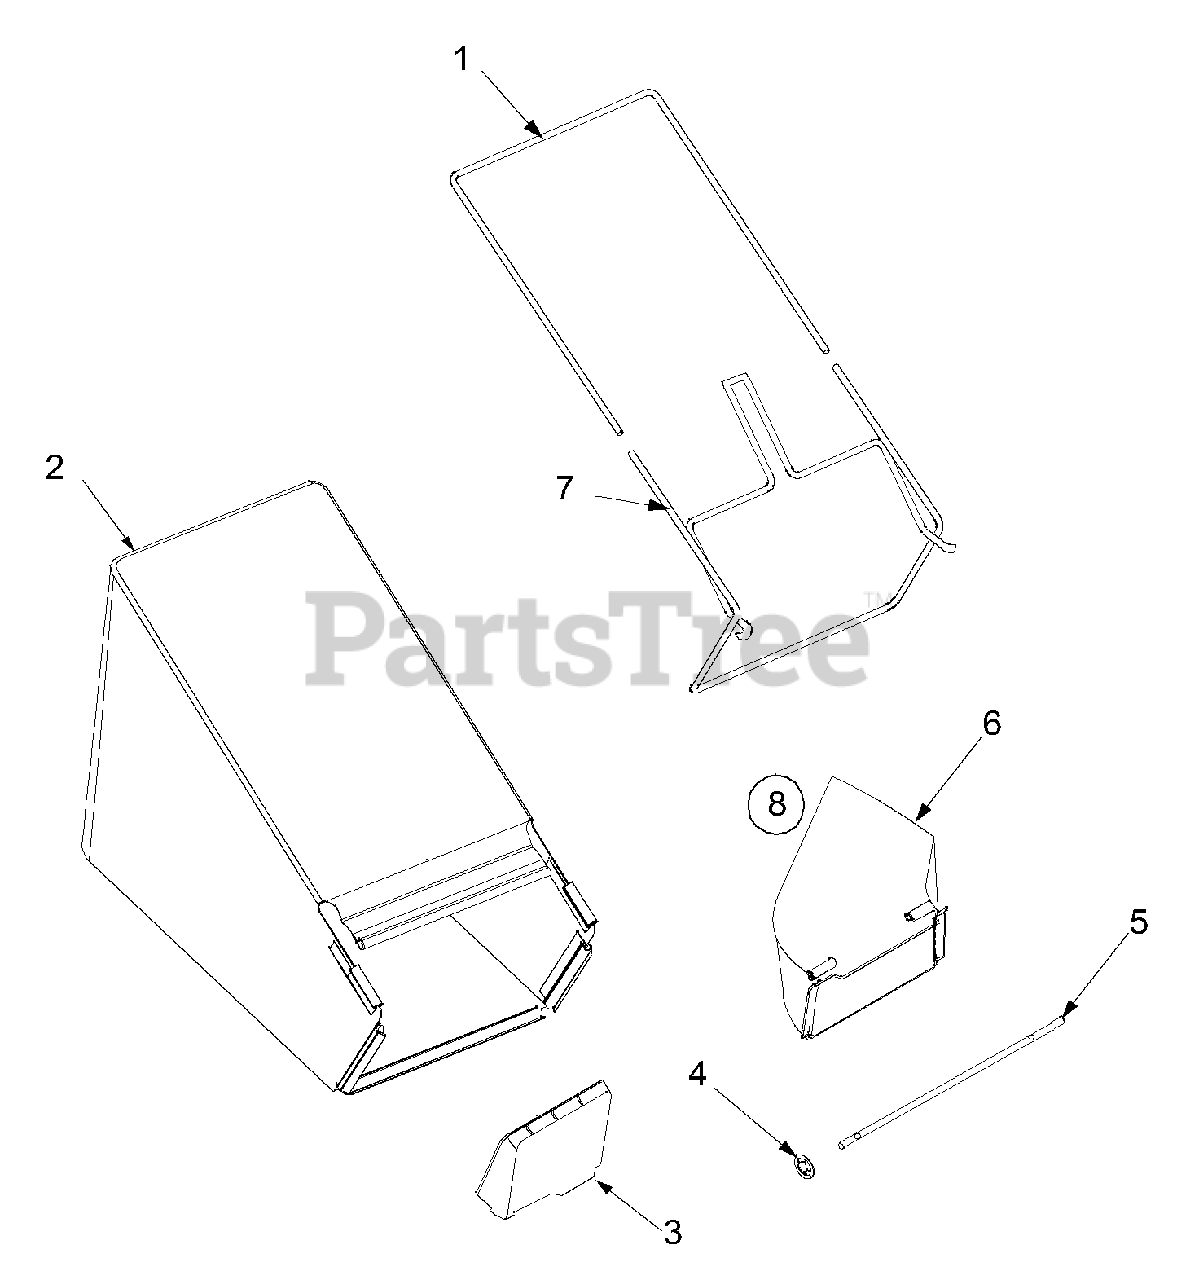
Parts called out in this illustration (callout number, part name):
2	Grass Bag: Soft Top w/o Logo
3	Mulcher Plug
4	Nut: Spd. .3125 ID
5	Rod
6	Side Discharge Adapter
